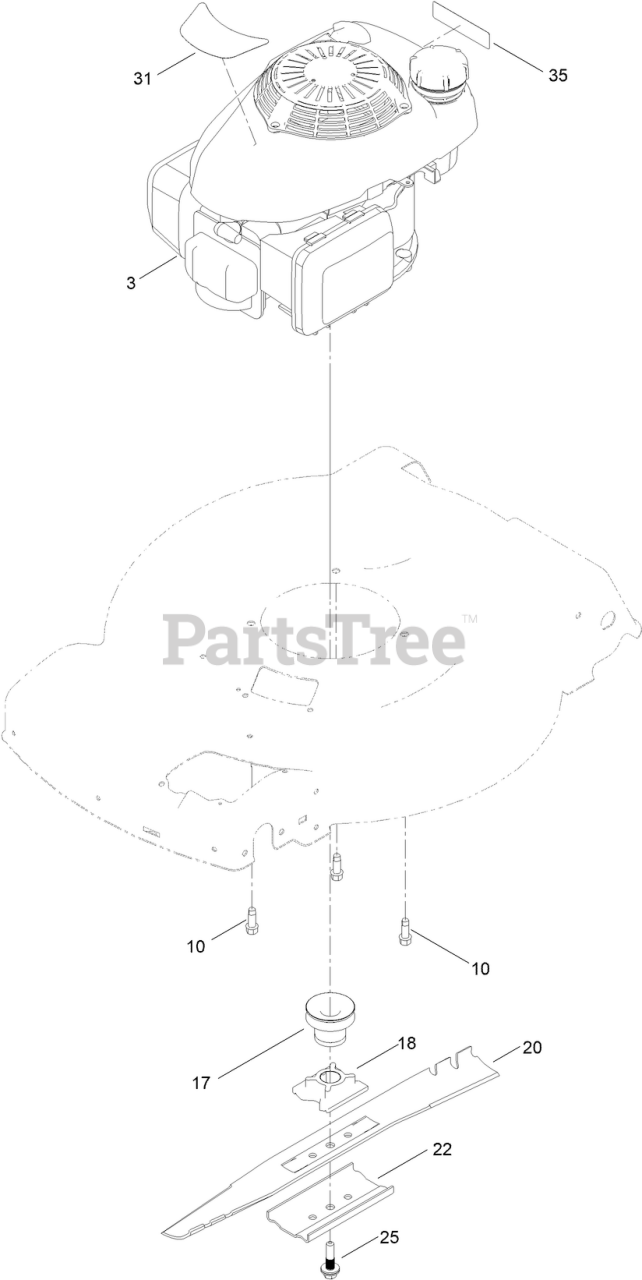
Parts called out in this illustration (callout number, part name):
10	SCREW-TAPTITE
17	DRIVER-BLADE
18	RETAINER-BLADE
20	BLADE-22 INCH
22	SUPPORT-BLADE
25	BOLT-BLADE
31	DECAL-ENGINE
35	DECAL-ARRESTOR, SPARK
